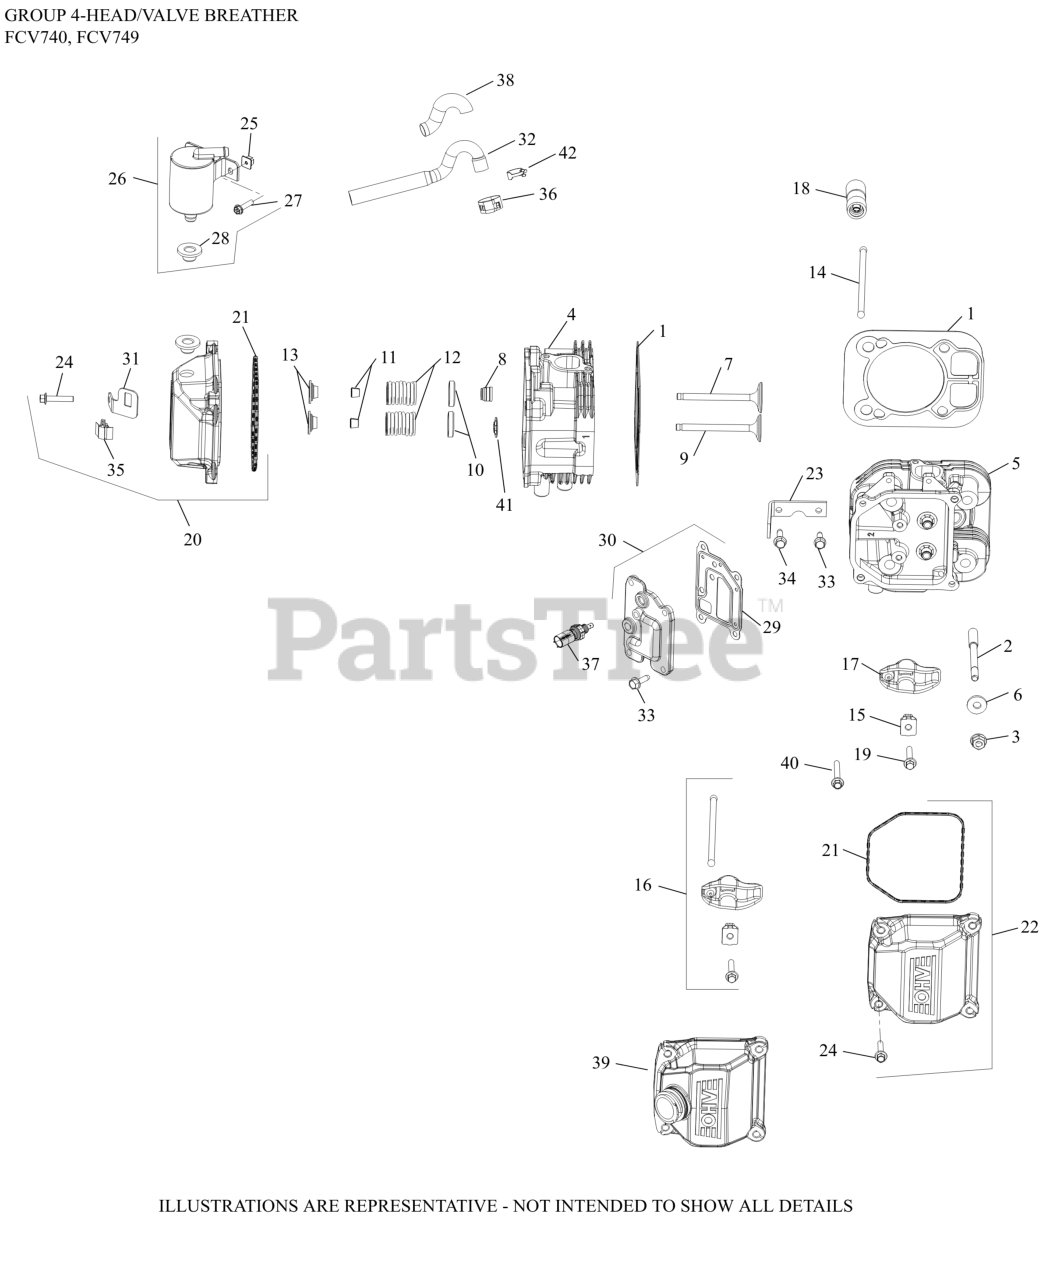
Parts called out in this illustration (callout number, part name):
1	KIT, GASKET CYLINDER HEAD
2	STUD, M8X1.25
3	NUT, FLG M8X1.25
4	KIT, CYLINDER HEAD #1-(#24318218S)
5	KIT, CYLINDER HEAD #2-(#24318219S)
6	WASHER, FLAT 8.6 MM
7	VALVE, INTAKE (STD)
7	VALVE, INTAKE (.25)
8	SEAL, VALVE BAND
9	VALVE, EXHAUST
9	VALVE, EXHAUST (.25)
10	RETAINER, SPRING
11	KIT, RETAINER
12	SPRING, VALVE
13	CAP, VALVE SPRING
14	ROD, PUSH
15	PIVOT, ROCKER ARM
16	KIT, VALVE TRAIN
17	ARM, ROCKER
18	LIFTER, VALVE HYDRAULIC-USE 25 351 11-S
19	SCREW, FLG (BLACK) M6X1.0X34
20	KIT, VALVE COVER
21	O-RING (YELLOW), VALVE CO
22	KIT, VALVE COVER-PLAIN (PLASTIC)
23	STRAP, LIFT
24	SCREW, FLG M6X1.0X30
25	NUT, PLASTIC
26	KIT, BREATHER SEPARATOR
28	GROMMET, RUBBER
29	GASKET, BREATHER
30	KIT, BREATHER COVER
31	BRACKET, OXYGEN SENSOR
32	HOSE, BREATHER
33	SCREW, THREAD FORMING
34	SCREW, THREAD FORMING
35	CLIP, O2 SENSOR
37	SENSOR, TEMPERATURE
38	SLEEVE, ANTI ABRASION-USE 25 431 12-S
41	RETAINER, VALVE GUIDE (KM)
